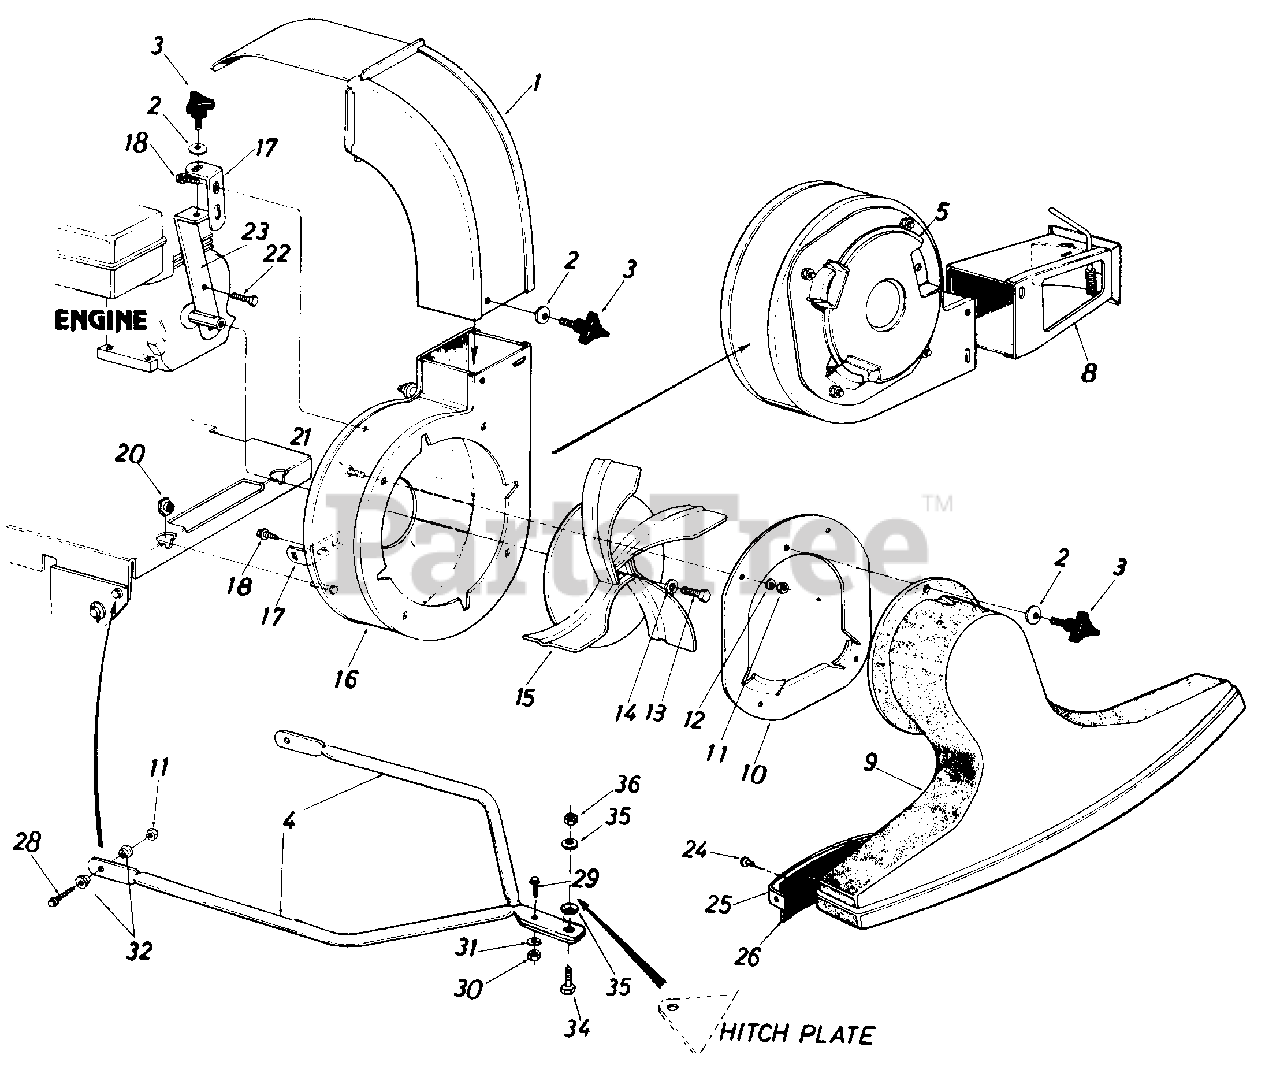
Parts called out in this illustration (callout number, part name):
3	3-Arm Thumb Scr. 5/16-18 x .75" Lg.
10	Nozzle Plate Ass' y .
11	Hex Nut5/16-18 Thd.
12	L. Wash. 5/16" I.D.
13	Hex Bolt 3/8-24 x 1.25" Lg.
14	L.-Wash. 3/8" I.D. H.D.
15	Air Vane Plate Ass y.
16	Blower Housing Complete
20	Hex Shoulder Nut .50 I.D.
21	Carriage Bolt 5/16-18 x .62 " Lg.
22	Hex Locking Bolt 5/16-24 x .75" Lg.
28	Hex Bolt 5/16-18 x 1.00" Lg.*
29	Truss Mach. Scr. 1/4-20 x .75" Lg.*
30	Hex Nut 1/4-20 Thd.*
31	L.-Wash. 1/4" I.D.*
32	Shoulder Spacer
34	Shld. Bolt .496 Dia.
35	Belleville Wash. .39 I.D. x 1.12 O.D.
36	Hex Jam L-Nut 3/8-16 Thd.
